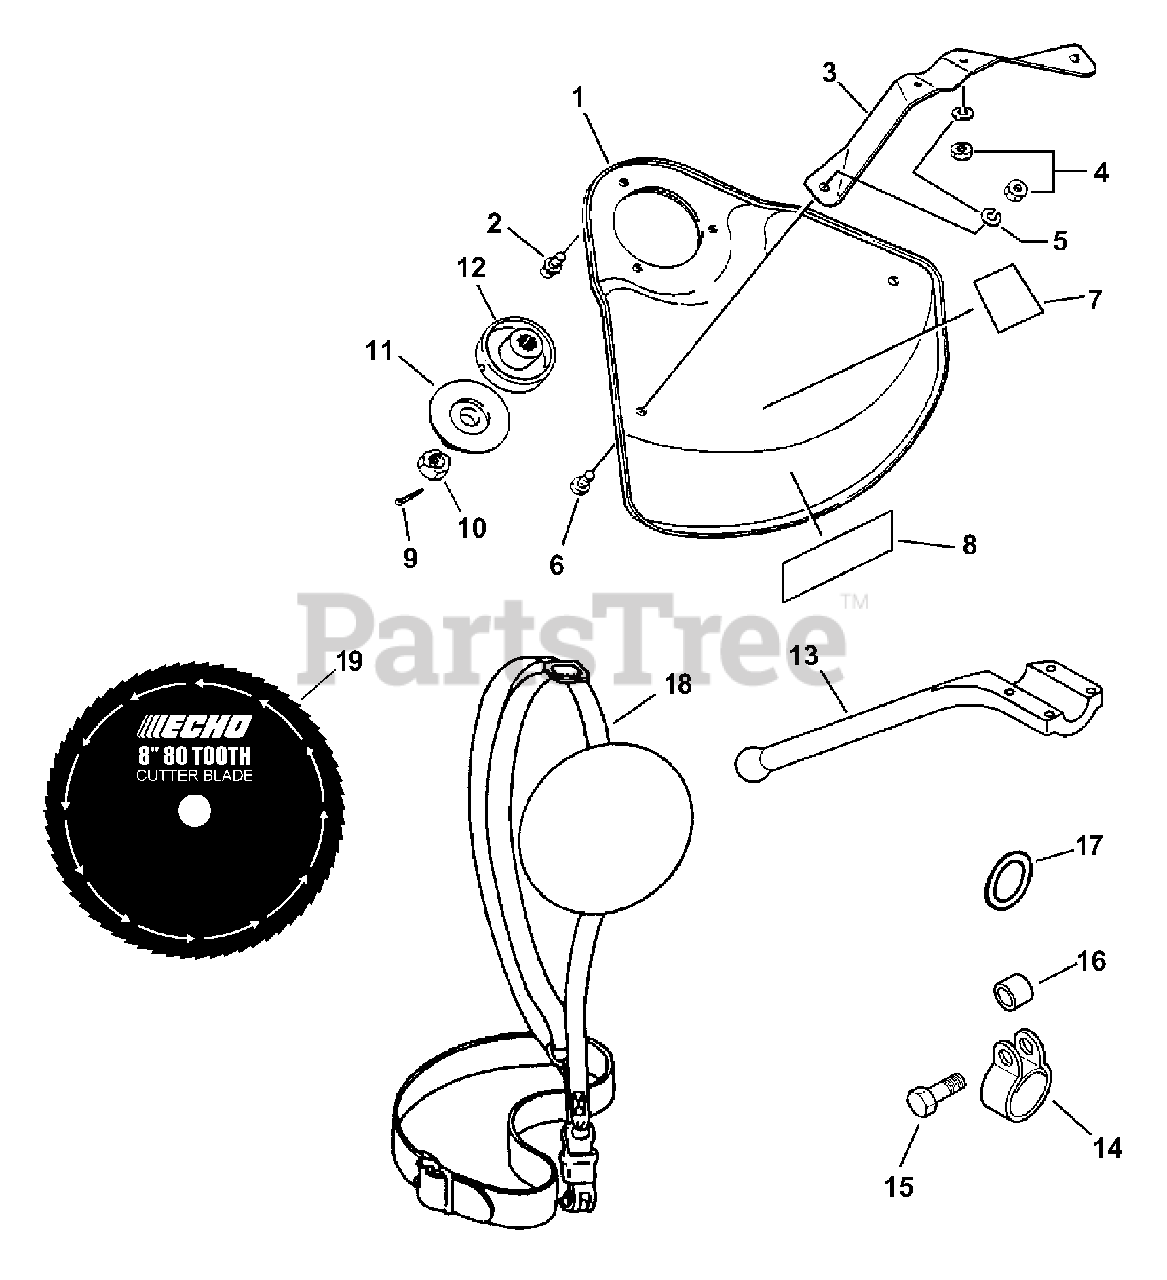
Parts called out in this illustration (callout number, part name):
1	SHIELD, DEBRIS - METAL
2	SCREW - 5X10
3	BRACKET, SHIELD
5	LOCKWASHER - 5
6	SCREW - 5X8
7	LABEL - DANGER
8	LABEL - ECHO
9	PIN, SPLIT - 2X22
10	NUT - 10 -- LEFT HAND
11	ADAPTOR, BLADE - LOWER
12	ADAPTOR, BLADE - UPPER
13	BAR, BARRIER
15	BOLT - 5X18
18	HARNESS ASSY
19	BLADE - 80 TOOTH -- 8" (20cm)
